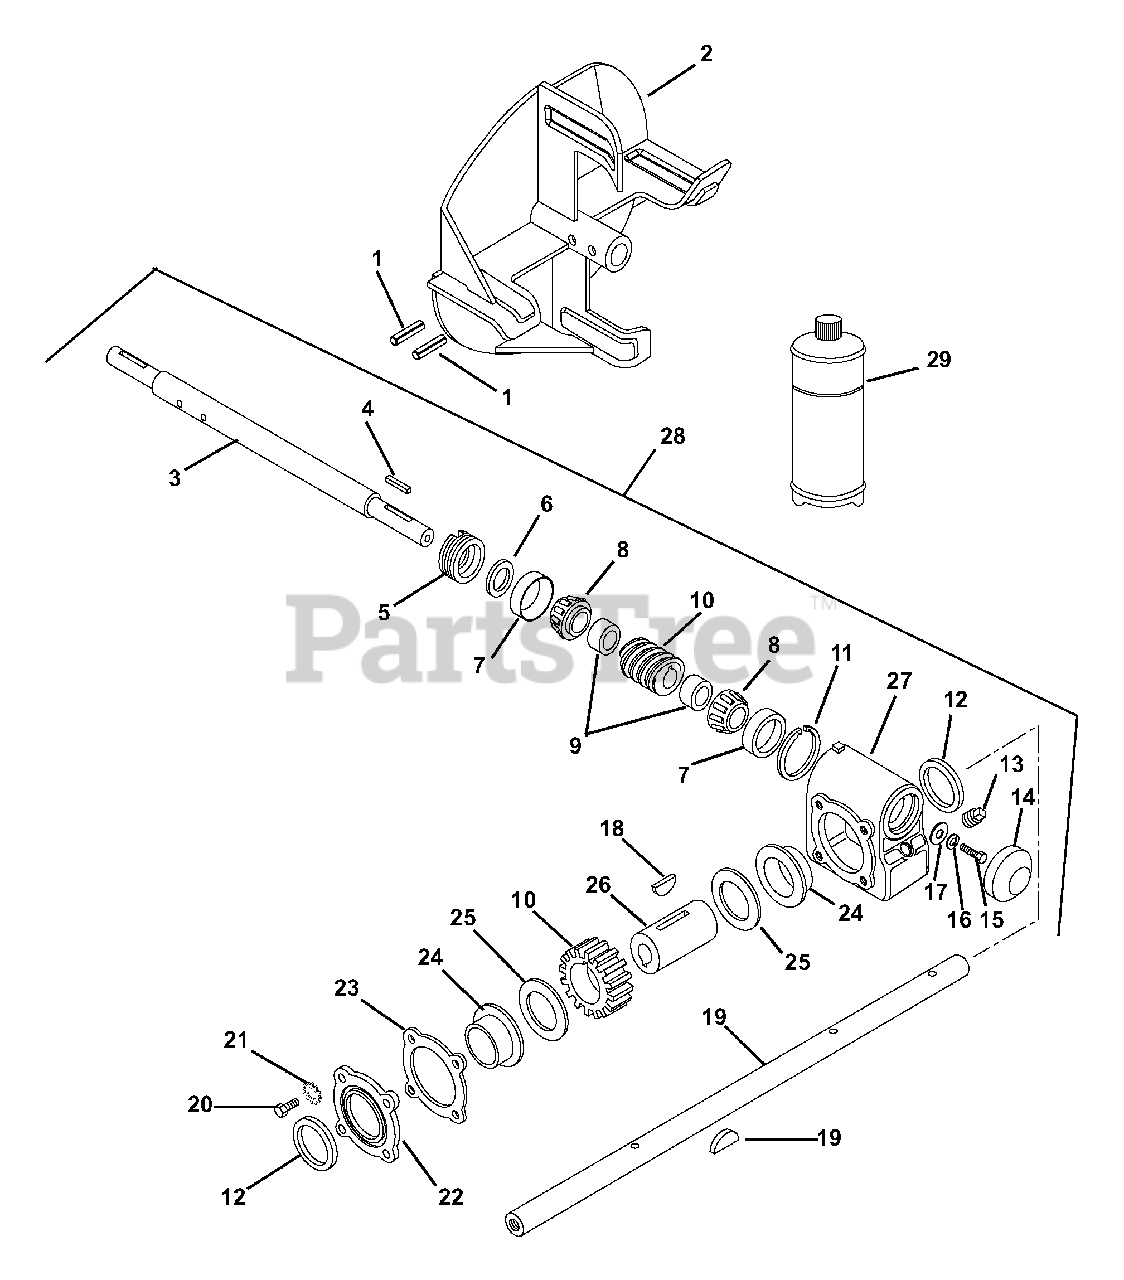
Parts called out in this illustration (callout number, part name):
1	PIN-ROLL .250X1.75
2	IMPELLER-14" 4 BLADE
2	IMPELLER-14" 6 BLADE
3	SHAFT, WORM
4	KEY-SQ .188X1.0X.188 SAE 8630
5	PLUG, ADJUSTMENT - .875 SHAFT
6	SEAL-OIL .875X1.25X.188
7	BRG-CUP 1.781X.475
8	BRG-CONE .750X.61
9	BSHG, SPCR .755X1.12X.50 PM
10	WORM & GEAR SERVICE ASSEMBLY
11	RG-RTNG-INT 1.781X.062
12	SEAL 1.625X2.125X.250
13	PIPE PLUG, 1/4 NPT
14	DUST CAP
15	@BLT-HEX .31-18X.75 GR5 YWZC
16	WSHR-LK .312X.097 HVY YWZC
17	WSHR-FL-STL .328X1.0X.094 YWZC
18	KEY-WDRF .25X.875X.375 SAE A
19	SHAFT, RAKE-26"
19	SHAFT, RAKE-28"
19	SHAFT, RAKE-32"
19	SHAFT, RAKE-36"
20	@BLT-HEX .25-20X.75 GR5 YWZC
21	@WSHR-LK-EXT.262X.502X.026YWZC
22	GEAR CASE COVER
24	BSHG-FLG .683X1.87X1.68X2.250
25	WSHR-FL-STL 1.625X2.500X.012
26	GEAR CASE SHAFT
27	GEAR CASE - CAST IRON
28	GEAR CASE,CAST IRON-.875 SHAFT
29	ARIENS 16 OZ.BOTTLE OF L2 LUBE
